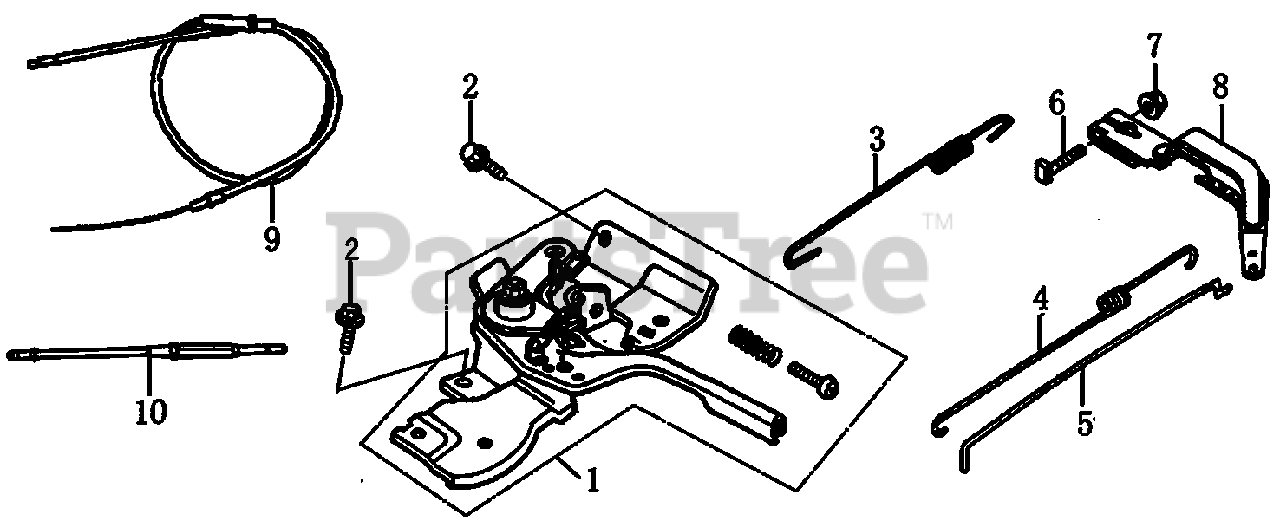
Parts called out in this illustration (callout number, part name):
1	CONTROL ASSY.
2	BOLT, FLANGE
3	SPRING, GOVERNOR
4	SPRING, THROTTLE RETURN
5	ROD, GOVERNOR
6	BOLT, GOVERNOR ARM M6X21
7	NUT, FLANGE
8	ARM, GOVERNOR
9	CABLE, CHOKE
10	PIPE, DRIVE
